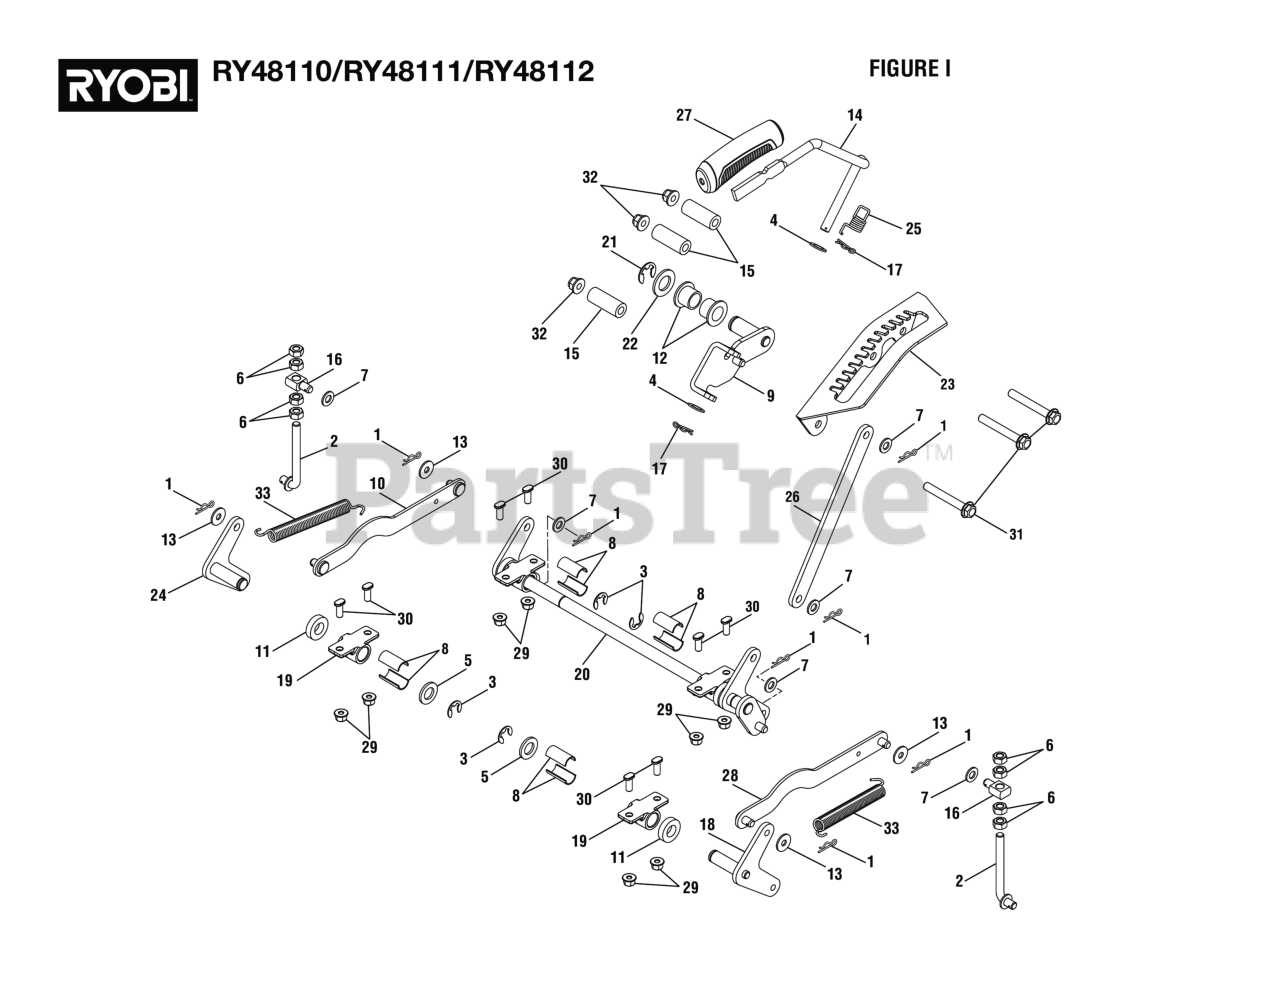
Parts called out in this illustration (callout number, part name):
1	Cotter Pin (10 mm)
2	Hanger Stud
3	E-Ring Clip (12 mm)
4	Washer (OD24 x ID13 x 2.5t)
5	Washer (OD30 x ID17 x 3t)
6	Nut (M10)
7	Washer (OD20 x ID10.5 x 2t)
8	Half Bushing Sleeve
9	Deck Lift Pivot Assembly
10	Right Linkage Assembly
11	Deck Lift Spacer
12	Pivot Plastic Sleeve
13	Washer (OD20 x ID10.5 x 2t)
14	Lever Rod
15	Spacer (10.5 x 20 x 51)
16	Hanger Stud Mount
17	Cotter Pin (12 mm)
18	Front Lifting Axle, Left
19	Frame Mount Hanger Bracket
20	Rear Lifting Axle
21	E-Ring Clip (15 mm)
22	Washer (OD37 x ID21 x 0.3t)
23	Detent Plate (4 mm)
24	Front Lifting Axle, Right
25	Torsion Spring
26	Deck Lift Lever Double Link
27	Decklift Handle
28	Linkage Assembly, Left
29	Flange Nut (M8) (For Drive Motor Controller V)
30	Bolt (M8 x 25 mm, Flush Mount)
31	Flange Bolt (M10 x 75 mm, Hex Hd.)
32	Lock Nut (M10 x 1.5 mm)
33	Tension Spring (Deck)
